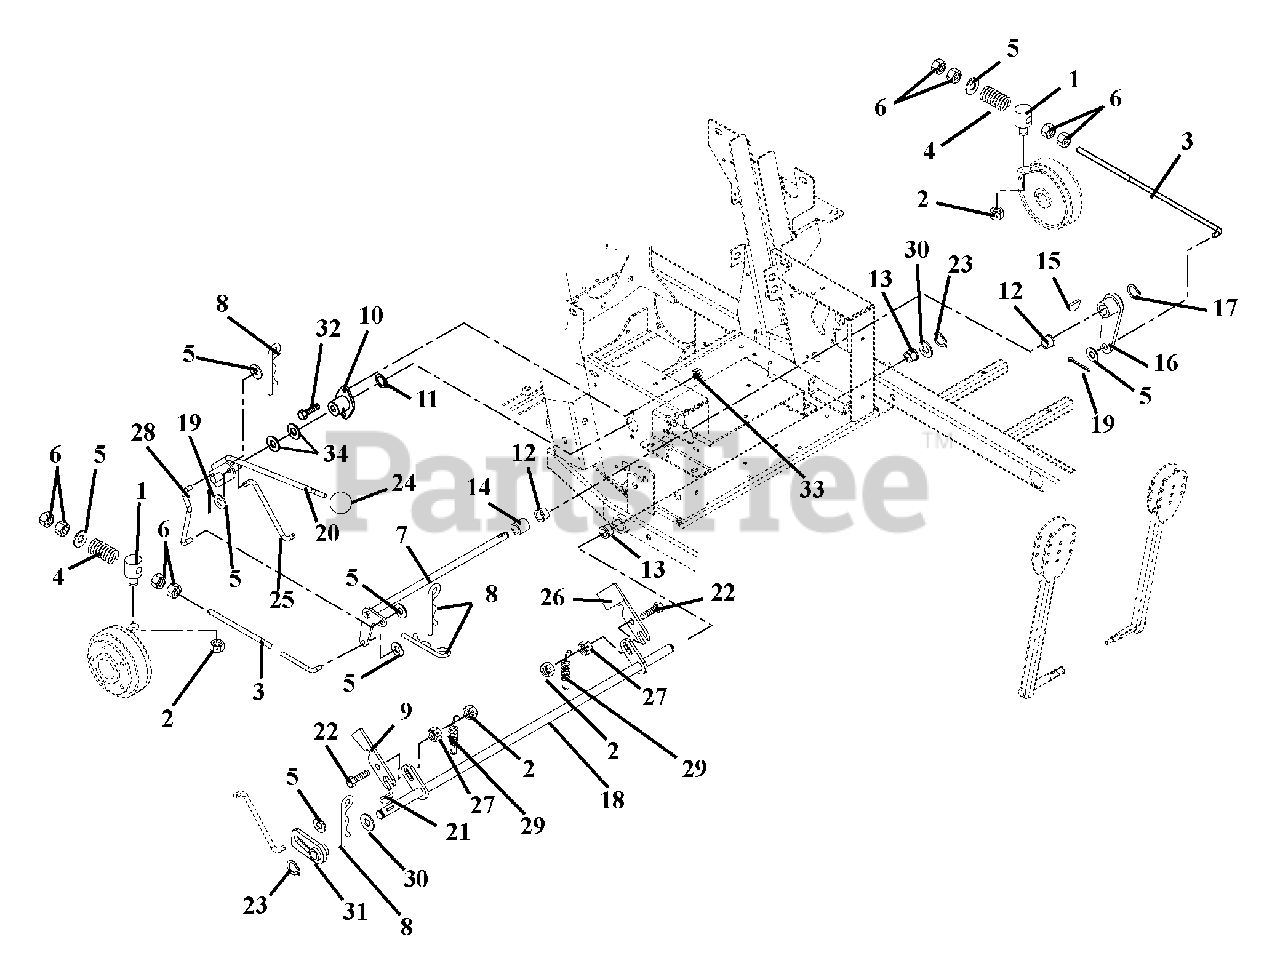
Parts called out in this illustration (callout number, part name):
1	Pivot, Brake Rod
2	Nut, Locking Center .31-18
3	PTO Link Rod
4	Spring, Compression .142 x .710 x 1.75
4	Spring, Compression .143 x .710 x 2.00
5	Washer, Flat Steel .406 x .812 x .065
6	Nut, Hex .38-16
7	Shaft, Brake Cross
8	Pin, Hair
9	Slide, Interlocking Brake
10	Bushing, Flange
11	Ring, Retaining External .625 x .05
12	Bushing, Flange Nylon .762 x 1.00 x .58 x 1.48
13	Bushing, Flange .515 x .75 x .745 x 1.00
14	Bushing, Sleeve .75 x 1.00 x .75
15	Key, Woodruff .19 x .75 Hard #9
16	Arm, Brake
17	Ring, Retaining External .69 x .077
18	Weldment, Mechanical Brake
19	Pin, Cotter External .09 x .75
20	Weldment, Brake Actuating
21	Key, Woodruff .13 x .63
22	Bolt, Round Head Square Neck .31-18 x 1.25 Grade 5
23	Ring, Retaining External .50 x .05
24	Knob, Steering Lock
25	Linkage, Brake Actuating
26	Interlock, Safety Switch
27	Nut, Locking Top Flange .31-18
28	Linkage, Brake Actuating
29	Spring, Tension .048 x .44 x 1.75
30	Washer, Flat Steel .505 x 1.00 x .062
31	Weldment, Parking Brake Hub
32	Bolt, Hex .31-18 x .75 Grade 5
33	Nut, Locking Top Flange .31-18
34	Washer, Flat Steel .630 x 1.25 x .062
